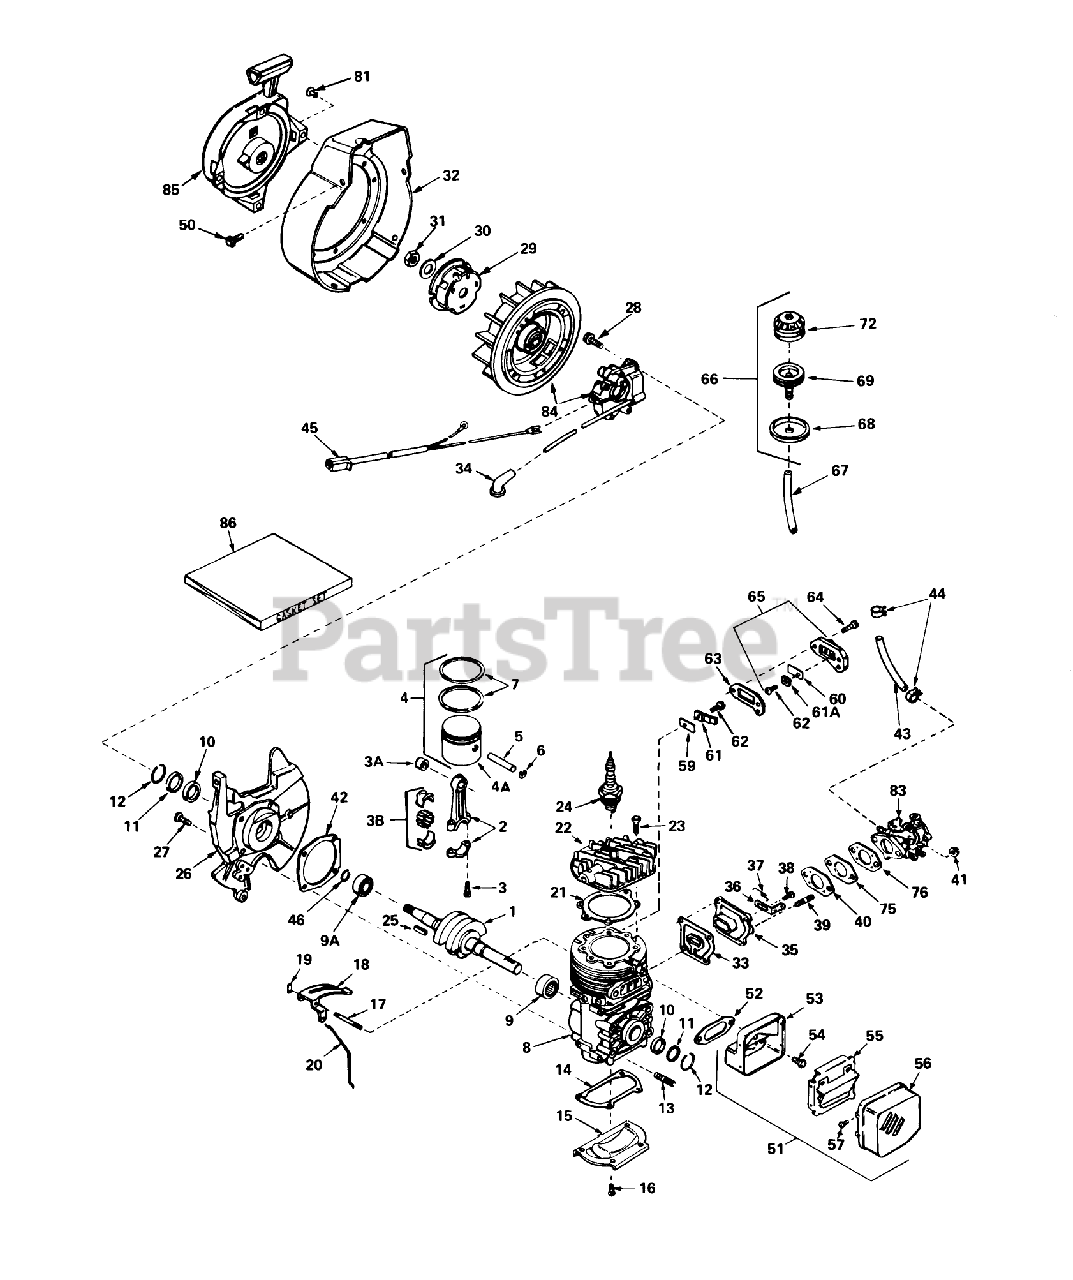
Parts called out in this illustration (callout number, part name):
1	Crankshaft
2	Rod Assembly, Connecting (Incl. #3, 3A 3B)
3	Bolt-Rod, Connecting
3A	Bearing-Cartridge
3B	Bearing Liner Set Needle
4	Piston, Pin Ring Assy. (Incl. Ref. #6 thru 9)
4A	Piston
5	Pin, Piston
6	Ring-Retaning
7	Ring Set
8	Block Assy., Cylinder (Incl. Ref. #9, 10 thru 13, 17 40)
9	Bearing-Cartridge
9A	Bearing-Ball
10	Seal, Crankshaft
11	Retainer, Crankshaft Seal
12	Spring, Crankshaft Seal Retainer
14	Gasket, Cover
15	Plate, Cover
16	Screw (T-25, 10-24 x 1/2)
17	Shaft, Air Vane
18	Vane Assy., Air
19	Clip,Air Vane
20	Link, Governor
21	Gasket, Head
22	Head-Cylinder
23	Screw (T-30, 1/4-20 x 3/4)
24	Head Adjustment Knob
25	Key-Flywheel
26	Base Assy., Housing (Incl. Nos. 29, 30 31)
27	Screw
28	Screw, Hex Washer Hd.
29	Starter Cup
30	Washer-Spring
31	Nut-Flywheel
32	Housing, Blower
33	Gasket, Port
34	Cover-Spark Plug
35	Adapter, Cover
36	Lever, Adjusting
37	Spring, Adjusting Lever
38	Screw
40	Gasket, Carburetor 1/8" thick)
41	Locknut
42	Gasket, Shroud Base
43	Line-Fuel (8.62)
44	Clamp-Line, Fuel
45	Harness, Wire
46	Ring, Retaining
50	Screw-Hex, Hd.
51	Muffler Assembly (Incl. #53-57)
52	Gasket-Muffler
53	Base-Muffler
54	Screw
55	Baffle, Muffler
56	Cover, Muffler
57	Screw
59	Reed, Compression Release
60	Reed, Compression Release
61	Plate, Reed Hold Down
61A	Plate, Reed Hold Down
62	Screw
63	Gasket, Compression Release
64	Screw
65	Cover Assy., Compression release (Incl. Nos. 60, 61A 62)
66	Primer Assy.
67	Line, Primer
68	Retainer, Primer Bulb
69	Body, Primer
72	Bulb-Primer
75	Spacer
76	Gasket, Carburetor (1/16"thick)
81	Rivet, Pop (3/16" dia.)(Can be purchased locally.)
83	Carburetor (Incl. No. 76)
84	Magneto
85	Starter-Rewind
86	Gasket Set (Incl. items marked *)
